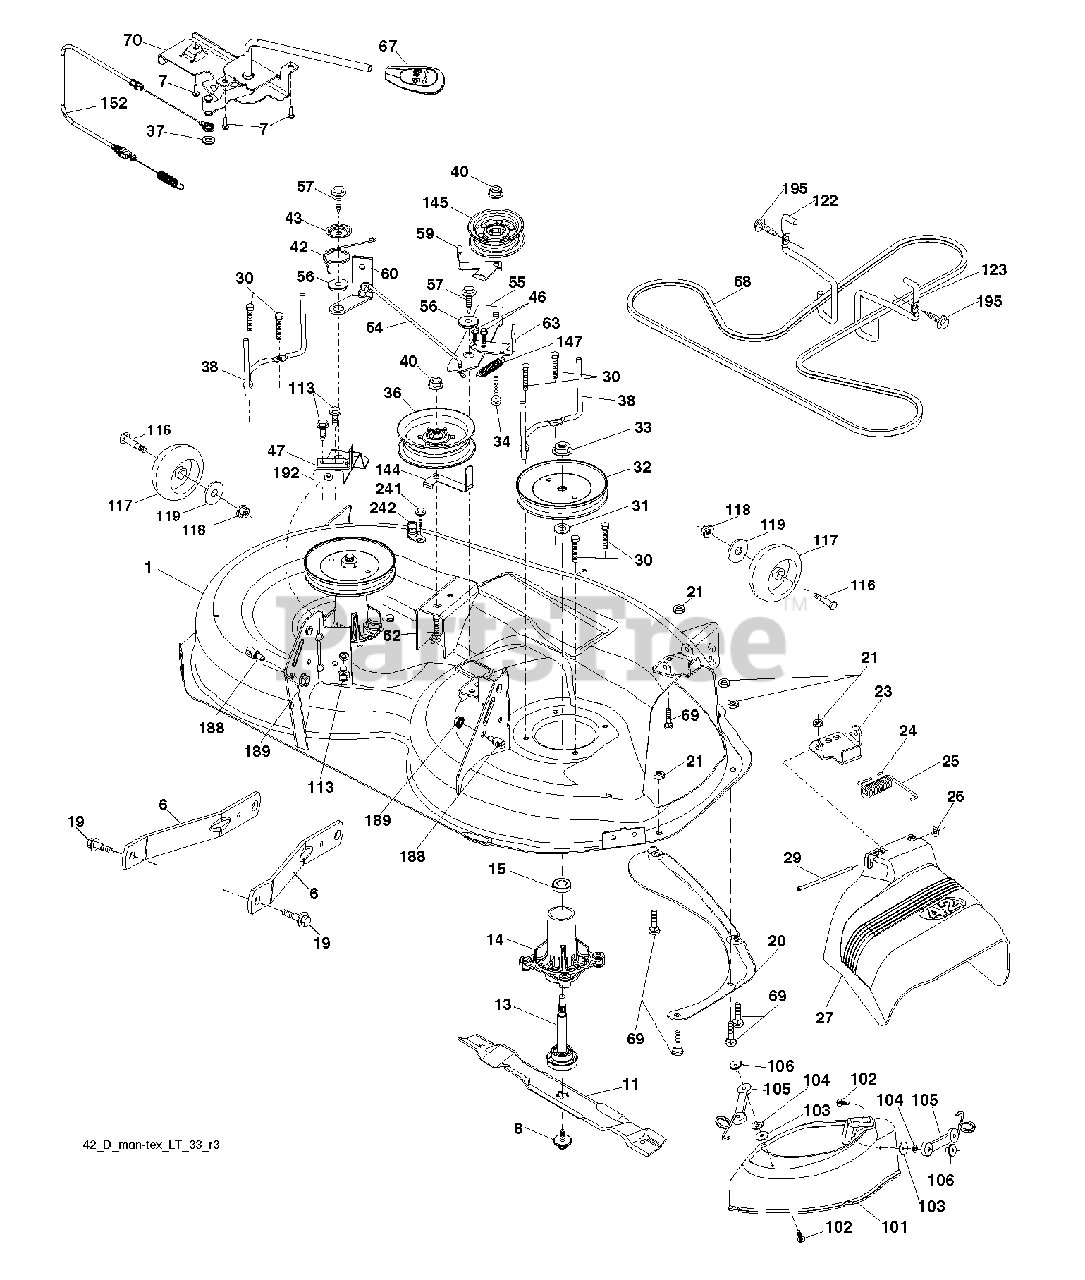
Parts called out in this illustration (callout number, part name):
1	DECK.WELDMENT.42"
6	ARM.SUSPENSION.MOWER.R
7	SCREW.#10 X 0.750.BOS THREAD
8	BOLT.WASHER.ASM.7/16-2
11	BLADE.42".MULCH
13	SHAFT.ASM.MDRL.N/GREASE.38
14	HOUSING MANDREL
19	BOLT.SHOULDER
20	BAFFLE.VORTEX
21	LOCKNUT
23	BRKT.DEFLECTOR.38"2005+
24	CAP-SLEEVE LT
25	SPRING.TORSION.DEFLECT
27	SHIELD.DEFLECTOR.MOWER.42"BLAC
29	ROD.HINGE
30	SCREW, WASHER HEAD
31	WASHER.SPACER.MANDREL
32	PULLEY.MANDREL.5.438.PD
33	NUT.FLANGE.LOCK.TOP
34	BOLT.3/8-16X1.50
36	PULLEY.IDLER.2006
38	KEEPER.BELT.MANDREL.PULLEY
40	NUT LOCK FLG 3/8-16 UNC
42	SPRING.TORSION.BRAKE
43	SRPING.TORSION.RETAINE
46	SCREW.1/4-20X5/8
47	BRKT.CLUTCH.CABLE
55	IDLER.ARM.42"
56	SPACER.RETAINER
57	SCREW 3/8-16X1
60	ARM BRAKE MOWER
62	BOLT
63	ARM BRAKE MOWER
64	LINK BRAKE
68	BELT.DECK.DRIVE.42"
69	BOLT
70	CLUTCH.ASM.MANUAL.LT.PRED
106	WELDNUT
113	BOLT.5/16HEX.WHS.HD
116	Shield Bolt, A 2.41 B 1.66
117	WHEEL.GAGE.HALF.SPOKED
118	LOCKNUT
119	WASHER
122	KEEPER BELT ENGINE LH
123	KEEPER BELT RH
144	KEEPER.BELT.MOWER
145	PULLEY.IDLER.48"PRIMARY
147	RETURN SPRING
152	CABLE.CLUTCH.MANUAL.
188	STUD.FASTNER.W/ANTI-ROTATE
189	NUT LOCK HEX FLANGE 5/16-18
192	BRKT.BRAKE.STAND.LH.
195	SCREW, 3/8-16X3/4
